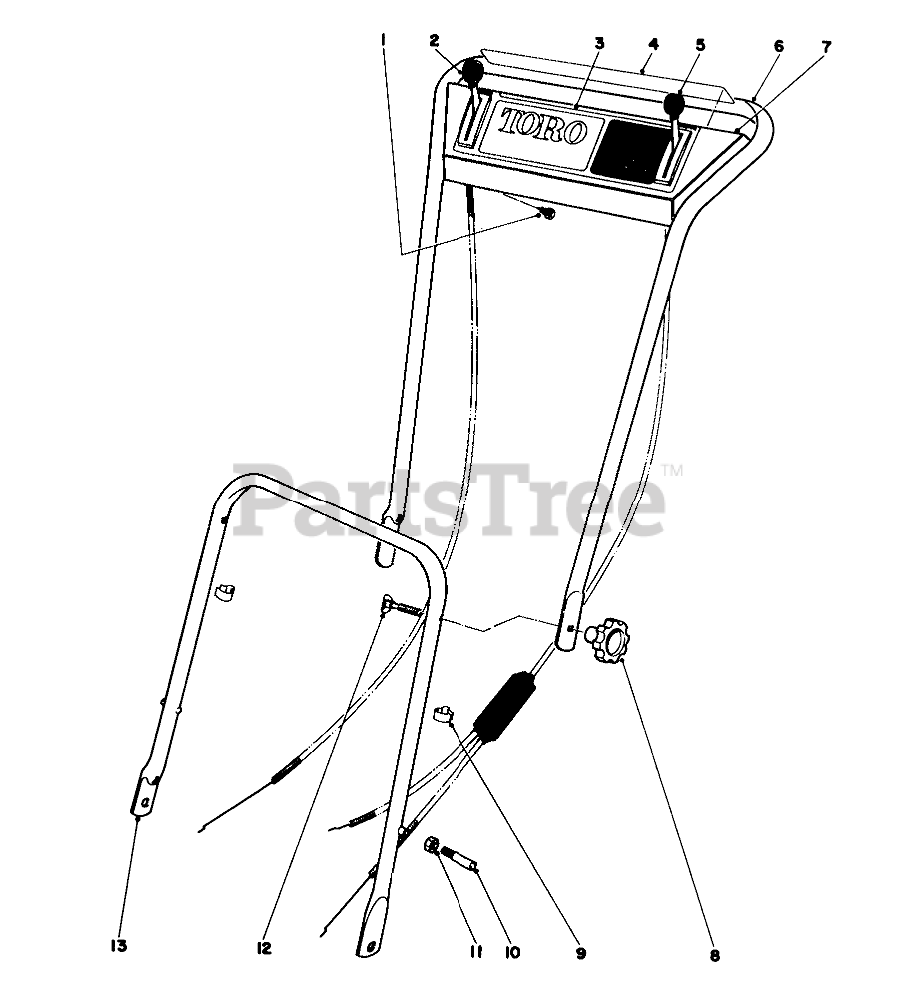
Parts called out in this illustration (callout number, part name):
1	Screw
2	Control-Throttle
3	Decal, Escutcheon Plate (Model 16273)
4	Decal Safety Instructions
5	Traction Control (Model No. 16273)
6	UPPER HANDLE
7	Escutcheon Plate (Model No.16273)
10	HANDLE PIN
11	Nut
12	SCREW-HANDLE
13	LOWER HDLE STKD ASM
